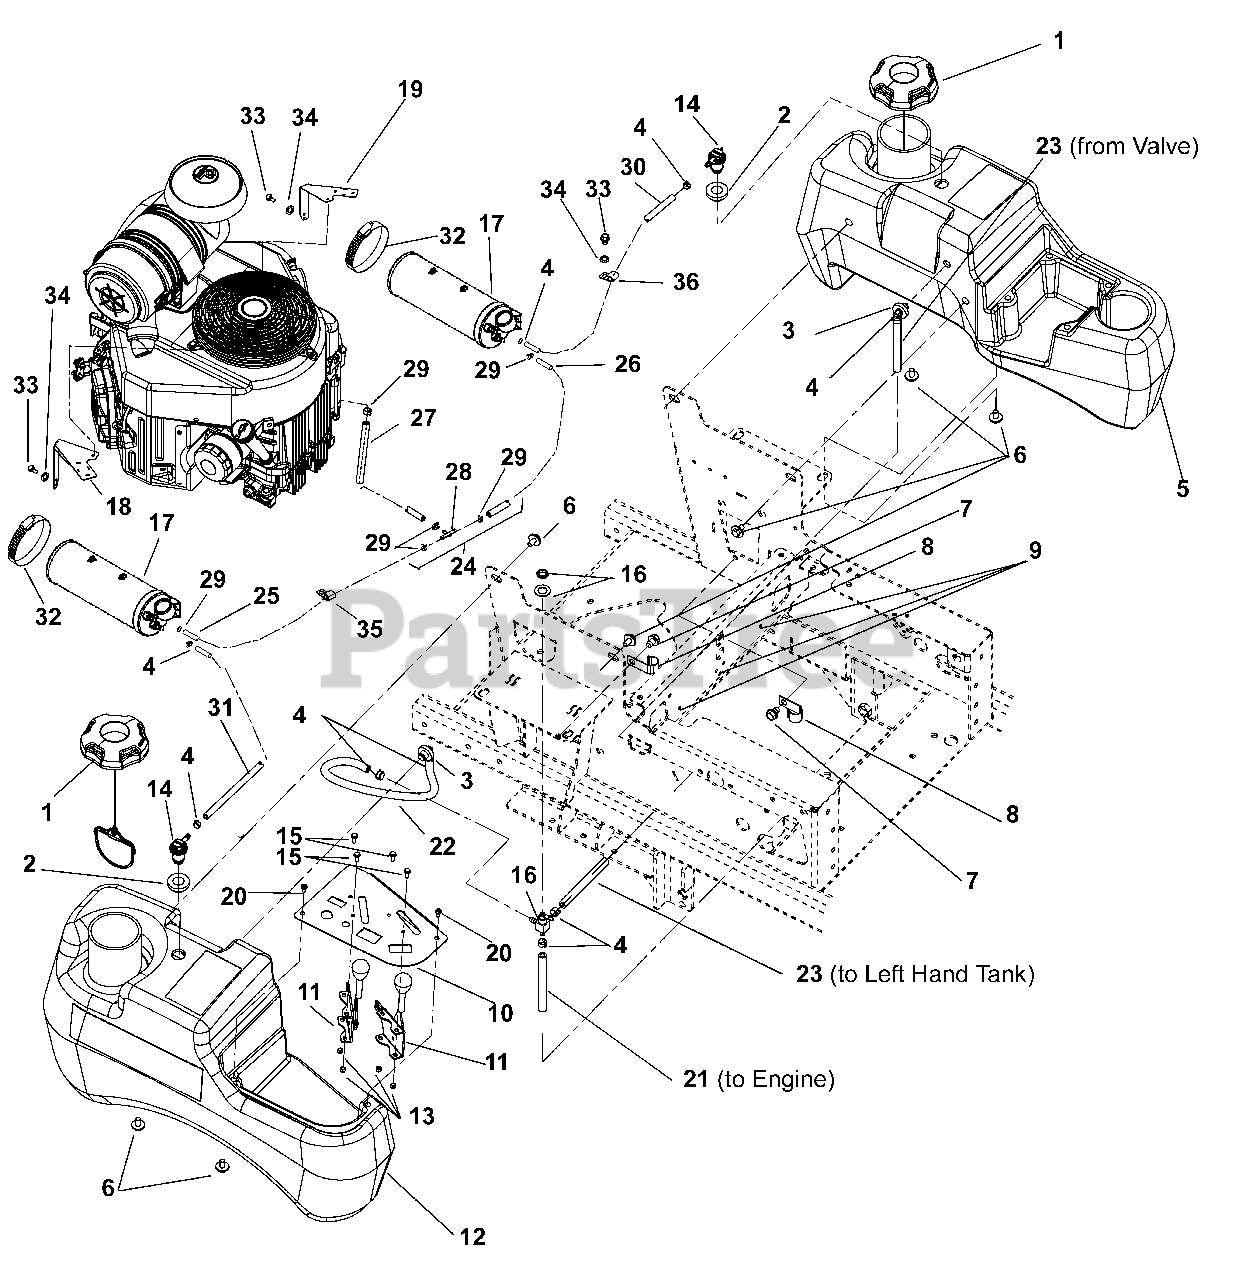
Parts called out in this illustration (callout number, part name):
1	Cap, Fuel Non-Vent Autolock
2	Grommet, Remote Vent Nitrile
3	Assembly, Medium Tank Fuel Pick-up
4	Clamp, Fuel Line
5	Tank, Left Hand Medium Gravely Fuel
6	Bolt, SEMS .31-18 x .62
7	Screw, Tapping Hex Washer Head Thread Rollin g.38-16 x .50
9	Cable Tie
10	PT100 Control Panel, Black
11	Cable, PT100 Throttle Control
12	Tank, RH Medium Gravely Fuel
13	Nut, Locking, Nylon 10-24 w/Insert
14	Valve, Combination
15	Screw, Machine Hex Washer Head 10-24 x .50
16	Valve, Fuel
17	Canister, Carbon 400cc
18	Bracket, Mount PT100 Carbon Canister Right Hand
19	Bracket, Mount PT100 Carbon Canister Left Hand
20	Screw, Machine HWH Stainless 10-24 x .38
21	Hose, .25 Low-Perm Bulk Gas (to Engine)
22	Hose, .25 Low-Perm Bulk Gas (to Right Hand Tank)
23	Hose, .25 Low-Perm Bulk Gas (to Left Hand Tank)
24	Assembly, Fuel Valve PT100CARB (includes items 25-29)
25	Hose, .188 Low-Perm Bulk Gas
26	Hose, .188 Low-Perm Bulk Gas
27	Hose, .188 Low-Perm Bulk Gas
28	Assembly, Fuel Line PT100 (CARB)
29	Clamp, Hose Spring .188
30	Hose, .25 Low-Perm Bulk Gas
31	Hose, .25 Low-Perm Bulk Gas
33	Bolt, Hex M8-1.25 x 20
34	Washer, Lock .31 x .078 Reg
35	Clamp Cushioned Steel
36	Clamp, Cushioned Steel .75
